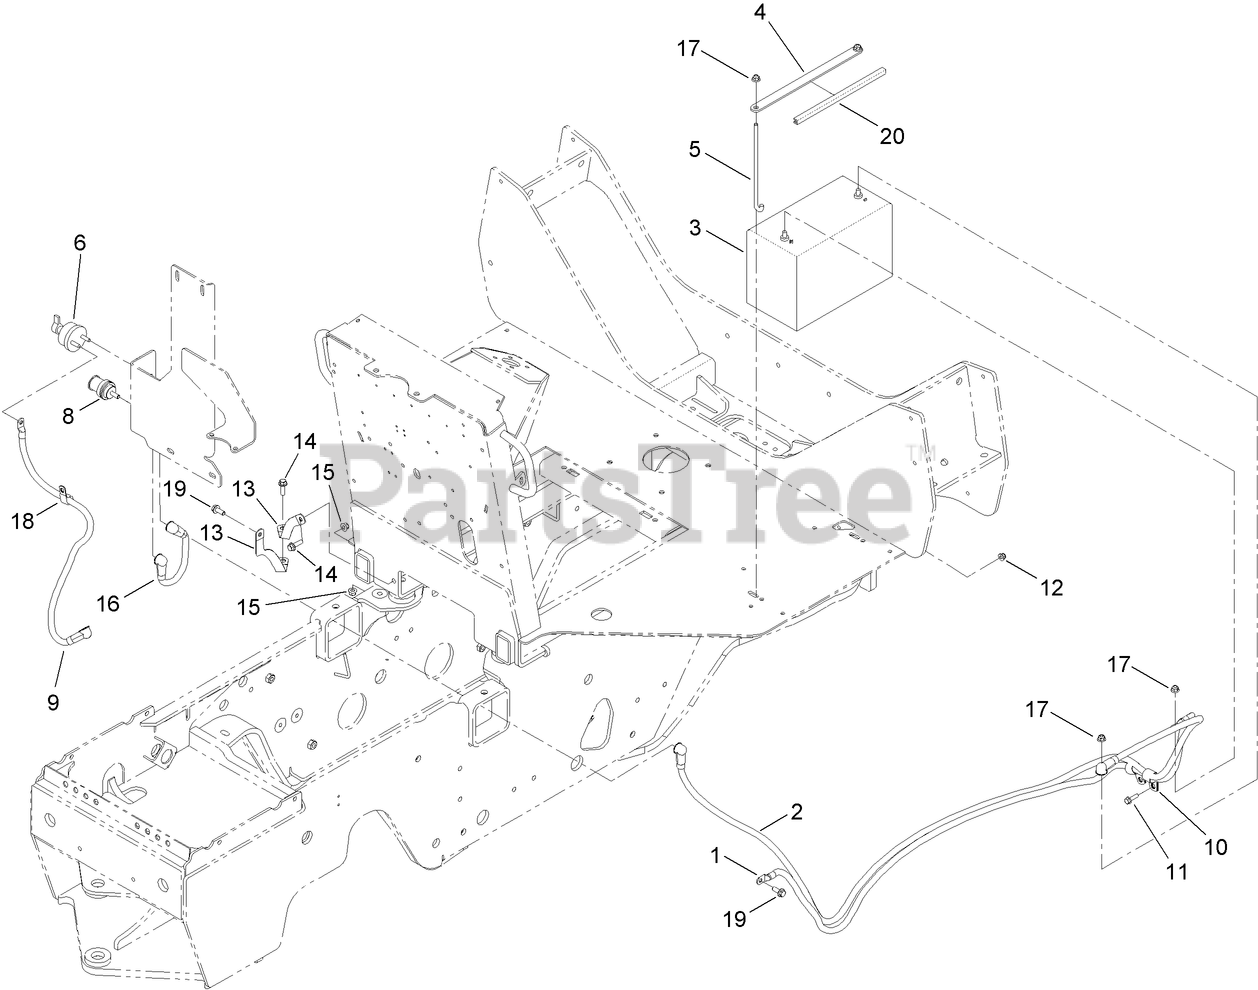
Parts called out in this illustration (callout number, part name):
1	CABLE-NEGATIVE
2	CABLE-BATTERY, POSITIVE
4	PLATE-HOLD DOWN, BATTERY
5	BOLT-HOLDDOWN, BATTERY
6	SWITCH-DISCONNECT, MASTER
8	POST-BATTERY, REMOTE
9	CABLE-Battery, Positive
10	CLAMP-R
11	SCREW-HHF
12	NUT-LOCK, HHF
13	STRAP-GROUNDING
14	SCREW-HHF
15	NUT-HF
16	CABLE-Positive
17	NUT-HF, NI
18	CLAMP-R
19	SCREW-HHF
20	TRIM-BATTERY
